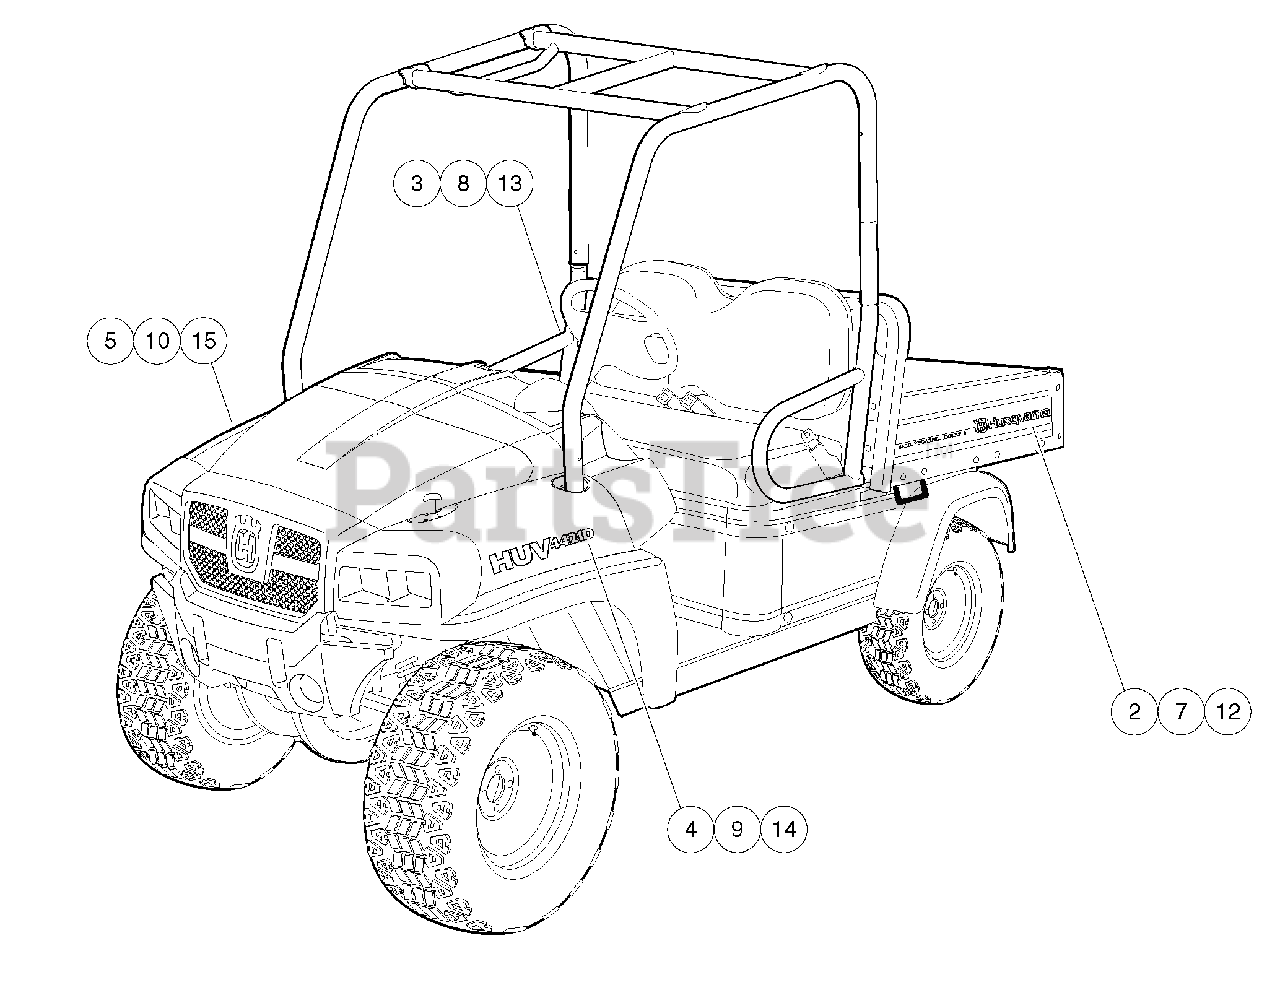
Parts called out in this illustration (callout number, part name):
1	Instl,decal,huv4421d, Moff
2	Decal, Bed, Huv, Moff, Ds
3	Decal, Bed, Huv, Moff, Ps
4	Decal, Huv 4421d, Moff, Ds
5	Decal, Huv 4421d, Moff, Ps
6	Instl,decal,huv4421d,orange
7	Decal, Bed, Huv, Orange, Ds
8	Decal, Bed, Huv, Orange, Ps
9	Decal, Huv 4421d, Orange, Ds
10	Decal, Huv 4421d, Orange, Ps
11	Instl,decal,huv4421d,olv Grn
12	Decal, Bed, Huv, Olv Grn, Ds
13	Decal, Bed, Huv, Olv Grn, Ps
14	Decal, Huv 4421d, Olv Grn, Ds
15	Decal, Huv 4421d, Olv Grn, Ps
